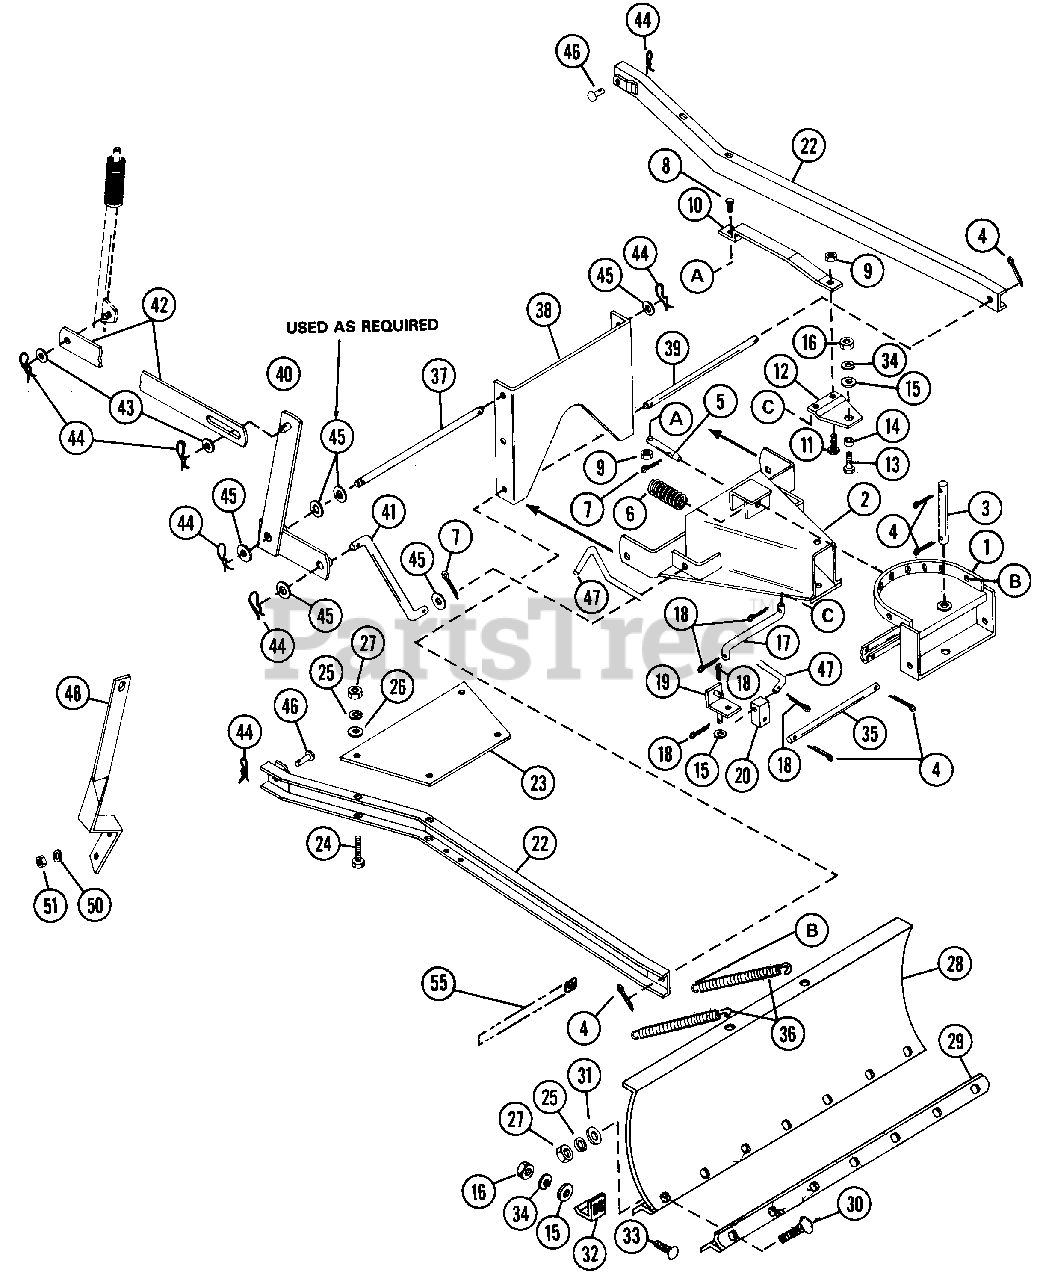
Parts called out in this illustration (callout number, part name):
1	SUPPORT
2	PUSH FRAME
3	ROD
4	COTTER PIN 3/16X1
5	LATCH PIN
6	COMP. SPRING
7	COTTER PIN 1/8X1
8	BOLT, HEX 5/16-18X1.25
9	LOCKNUT 5/16-18
10	STRAP
11	BOLT, CARRIAGE 5/16-18X5/8
12	PIVOT PLATE
13	BOLT, HEX 3/8-16X1
15	WASHER 3/8
16	NUT 3/8-16
17	ROD
18	COTTER PIN 1/8X.75
20	UNIVERSAL BLOCK JOINT
22	CHANNEL
23	STIFFENER PLATE
24	BOLT, HEX 5/16-18X2.50
25	LOCKWASHER 5/16
26	WASHER
27	NUT 5/16-18
28	BLADE
29	WEAR PLATE
30	BOLT, CARRIAGE 5/16-18X1
31	WASHER, 5/16
32	SKID SHOE
33	BOLT, CARRIAGE 3/8-16X1
34	LOCKWASHER 3/8
35	ROD
36	EXTENSION SPRING
37	MOUNT ROD
38	PIVOT SUPPORT
39	PIVOT ROD
40	LIFT BELLCRANK
41	LIFT LINK
42	LIFT STRAP
43	WASHER 1/2
44	HAIR PIN, INTERNAL
45	WASHER 5/8
46	CLEVIS PIN
47	CONTROL ROD
48	CONTROL SUPPORT
50	LOCKWASHER 5/16
51	NUT 5/16-18
55	DECAL
